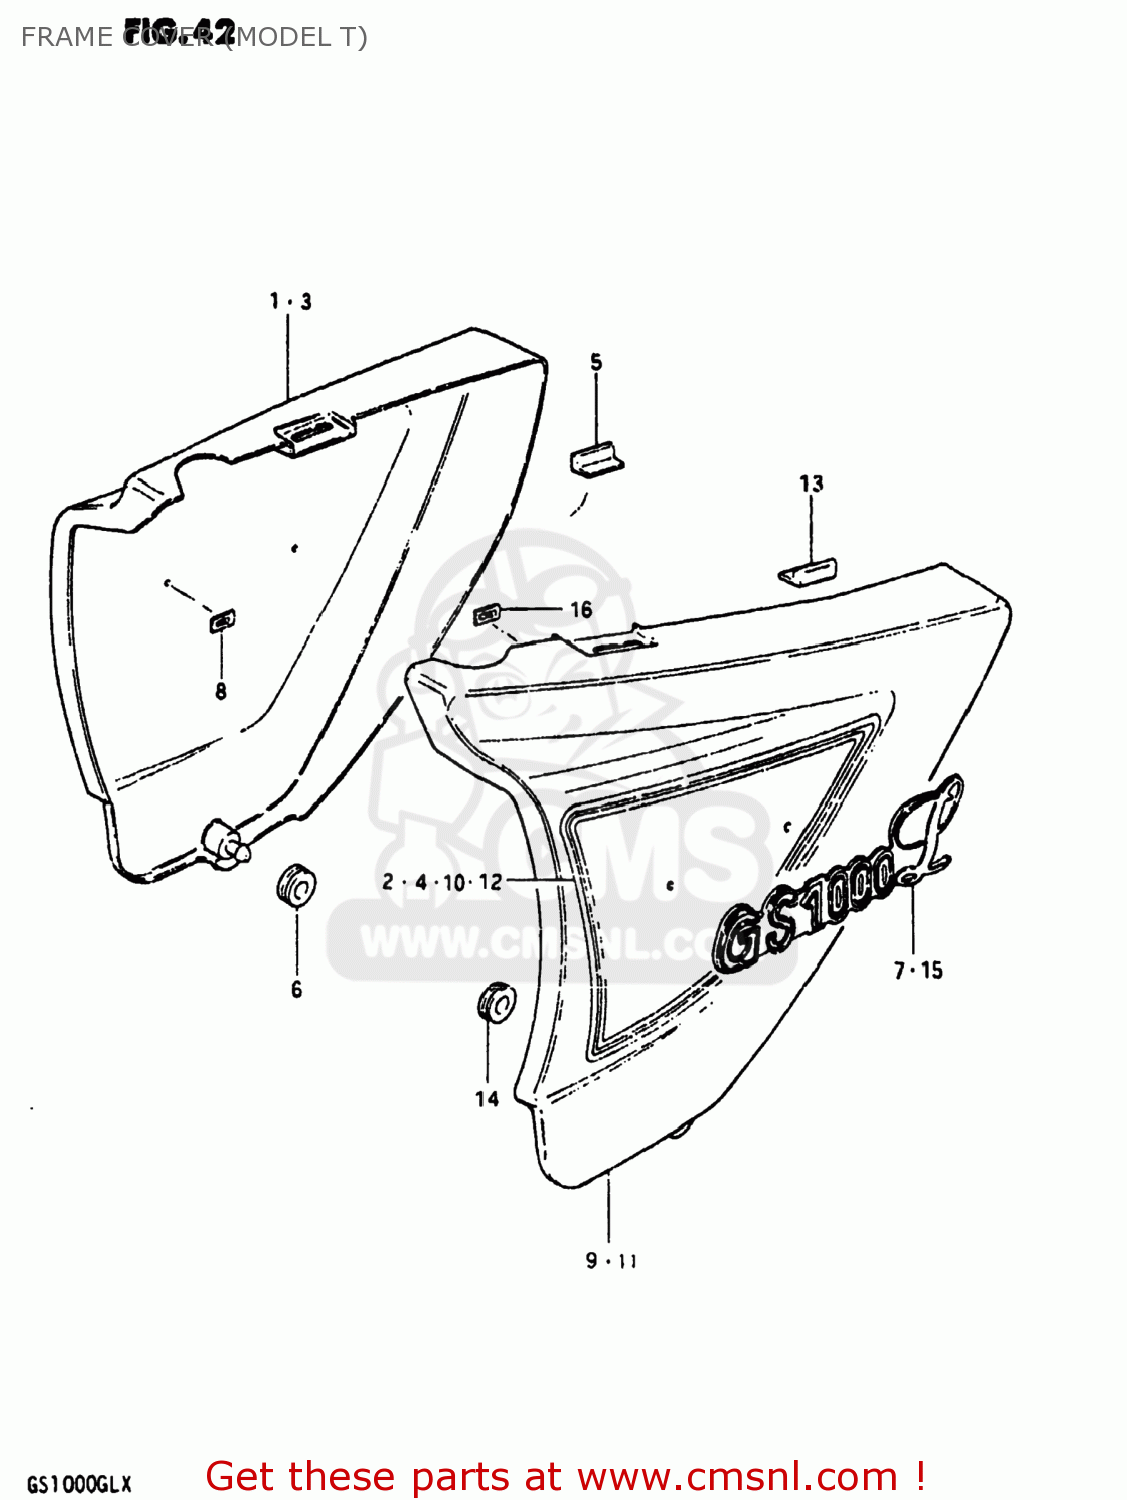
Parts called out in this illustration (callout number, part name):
1	COVER ASSEMBLY,FRAME,RIGHT
2	TAPE SET,FRAME COVER
3	COVER ASSEMBLY,FRAME,RIGHT
4	TAPE SET,FRAME COVER
5	CUSHION,FRAME COVER
6	CUSHION
7	EMBLEM,FRAME COVER
8	NUT
9	COVER ASSEMBLY,FRAME,LEFT
10	TAPE SET,FRAME COVER
11	COVER ASSEMBLY,FRAME,LEFT
12	TAPE SET,FRAME COVER
13	CUSHION,FRAME COVER
14	CUSHION
15	EMBLEM,FRAME COVER
16	NUT
